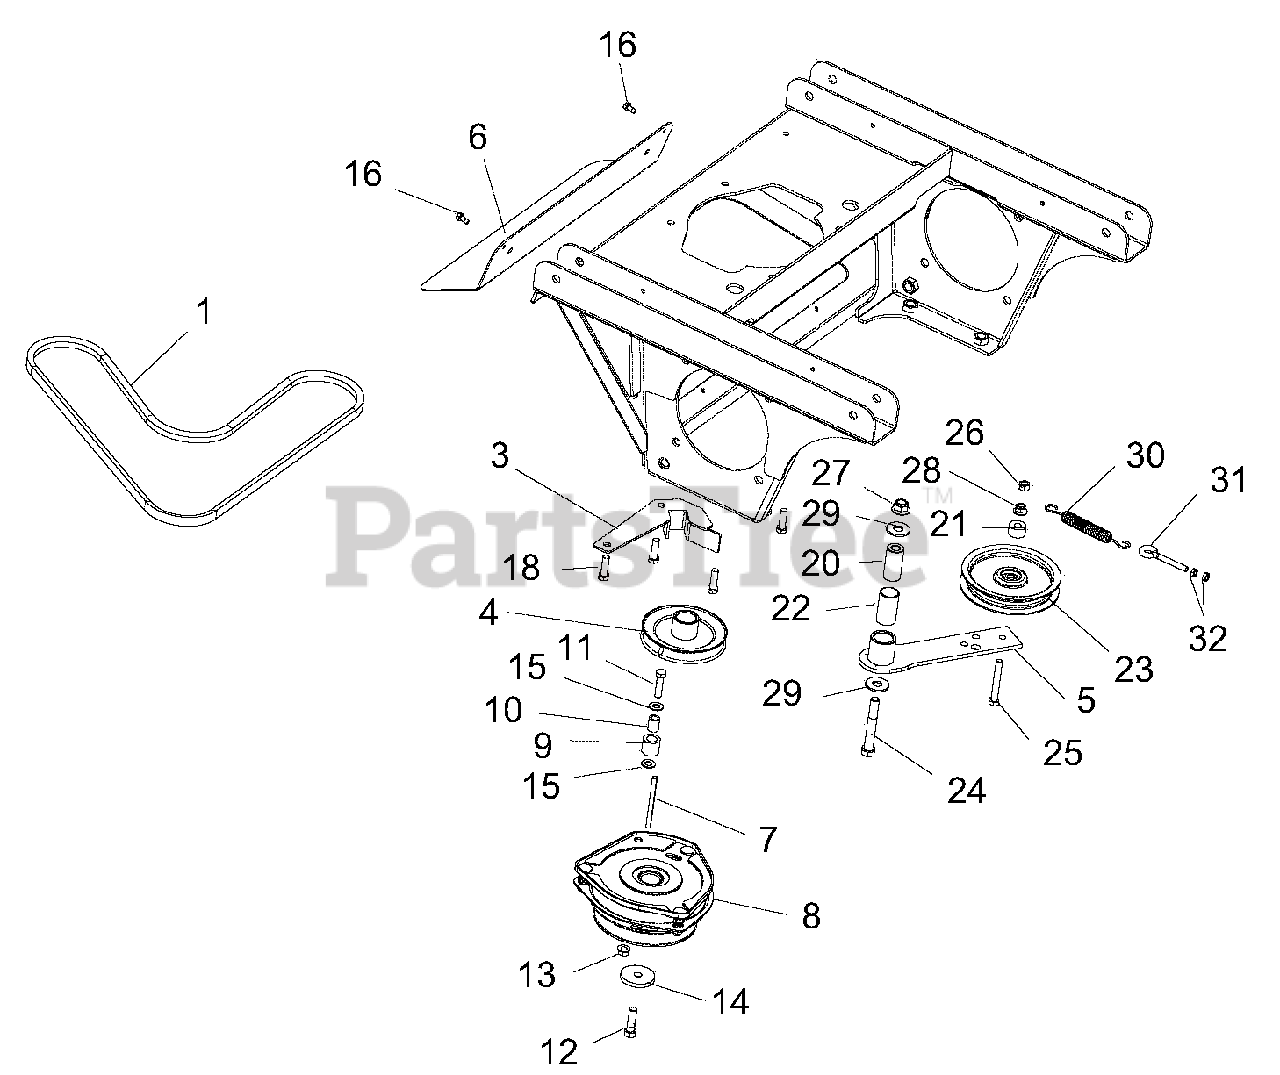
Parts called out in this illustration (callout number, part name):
1	BELT, B RAW COGGED
3	WMT, CLUTCH STOP
4	SHEAVE, ENGINE 1.127ID X 5.25OD
5	WMT, IDLER ARM GROUND
6	SHIELD, MUFFLER HEAT
7	KEY-SQ .250X.250X3.50
8	CLUTCH-OGURA
9	BUMPER, RUBBER .62 X 1.0 X.88 LG
10	BUSH., S .407X.625X.813 ST
11	BLT-HEX .38-16X1.50 GR5 YWZC
12	BLT-HEX .44-20X1.50 G5 YZ EP80
13	NUT, LK-TOP-FLG .38-16 YWZC
14	WSHR-FL-STL .469X2.00X.25 YWZC
15	WSHR-FL-STL.406X.812X.065 YWZ
16	SCR-TAP .25-20X.50 HWH TR YWZ
18	BLT-HEX .38-16X1.25 FTH GR5 EP80
20	BSHG, SPCR .502X.997X2.03
21	SPACER .390X1.00X.562
22	BSHG, 1.00X1.125X1.937
23	IDLER, FLAT 5.00 X 3.8
24	BLT-HEX .50-13X3.50 GR5 YWZC
25	BLT-HEX .38-16X2.75 GR5 YWZC
26	NUT-LK-CTR .38-16 YWZC
27	NUT-LK-NYL-FLG .50-13 YWZC
28	NUT-LK-NYL-FLG .38-16 YWZC
29	WSHR-FL-STL.563X1.38X.109YWZC
30	SPRING, EXTENSION
31	BOLT, EYE .375-16 X 2.50 YWZC
32	NUT, HEX-JAM .375-16 YWZC
